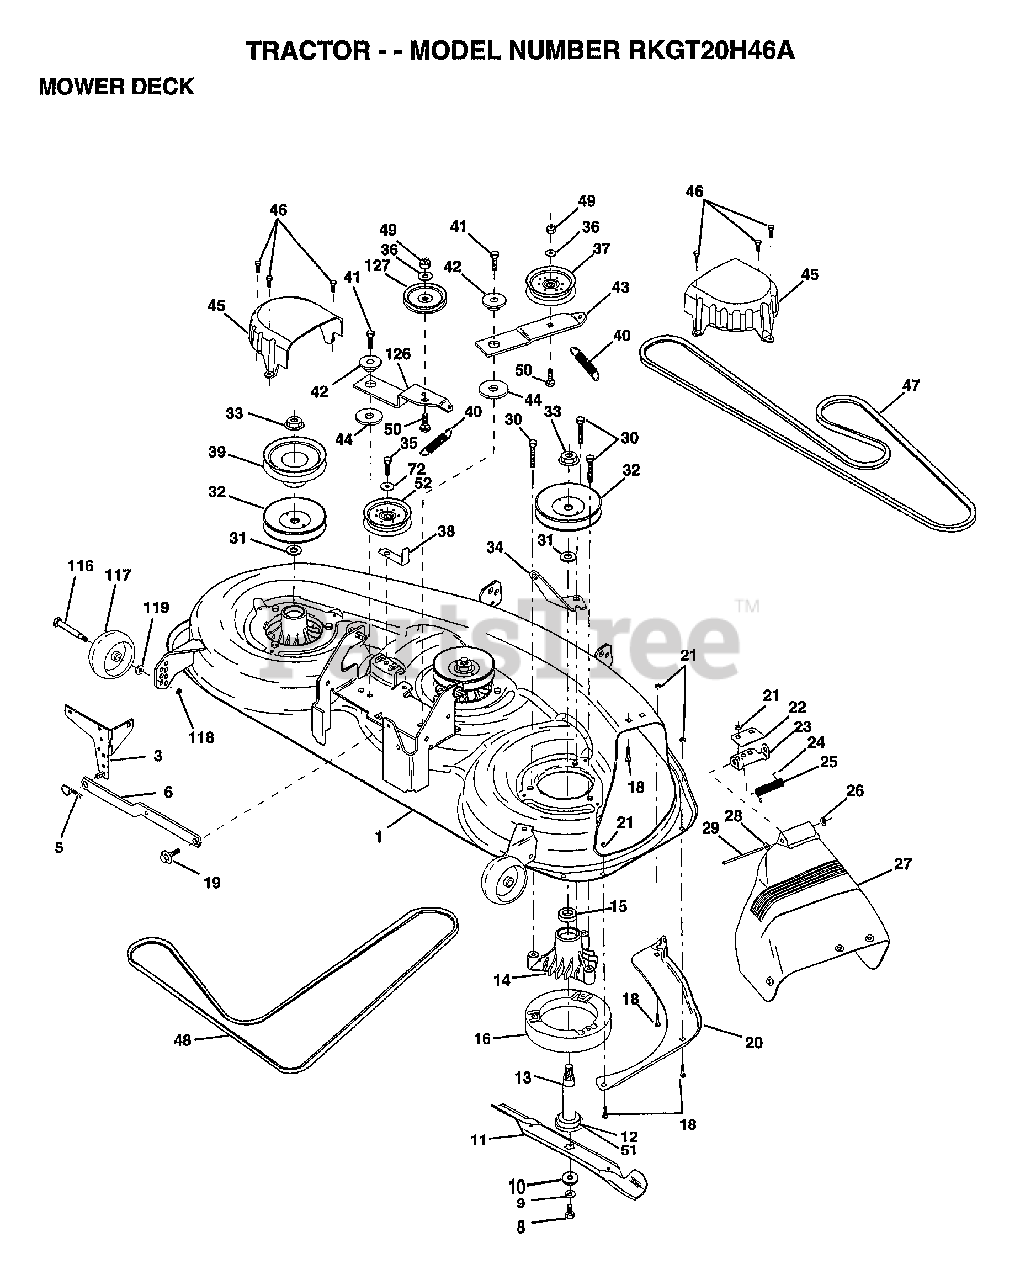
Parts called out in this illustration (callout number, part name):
1	"DECK.ASM.MOWER46"""
3	BRKT.ASM.SW.44/50
8	BLADE BOLT
10	WASHER.HARD.BLADE
11	"BLADE MULCH 46"""
12	BEARING.BALL
13	SHAFT.ASM.W/BRNG
14	HOUSING.MAND.44.V
15	BEARING
16	STRIPPER RND MWR
18	BOLT
19	BOLT SHD 5/16-18
20	BAFFFLE.VORTEX.46
22	STIFFENER BRKT
23	DEFLECTOR BRKT
24	CAP-SLEEVE LT
26	NUT PUSH M
27	SHIELD DEFLECTOR
28	WASHER
29	HINGE ROD
30	"SCREW-THD ROLL,WA"
31	WASHER
32	PULLEY.MAND.36/46
34	ANCHOR.SPRING.46
35	SCREW LT
36	WASHER
37	FLAT IDLER PULLEY
38	"KEEPER BELT,IDLER"
39	PULLEY.DRV.DCK.46
40	"SPRING.SEC.44""VEN"
41	SCREW
42	SPACER RETAINER
43	ARM.IDLER.DECK.46
44	HARDENED WASHER
45	COVER.MANDREL.46
46	SCREW.1/4-20X5/8
47	BELT-V.SEC.46.KEL
48	BELT.MWR.PRM.85.4
50	BOLT.3/8-16X1.50
51	WASHER.FELT.
52	"PULLEY IDLER,FLAT"
72	WASHER HYT
116	BOLT.SHOULDER
117	WHEEL GAGE DONUT
118	LOCKNUT
119	WASHER
126	ARM.IDLER.PRIM.46
127	PULLEY.IDLER.4.25
